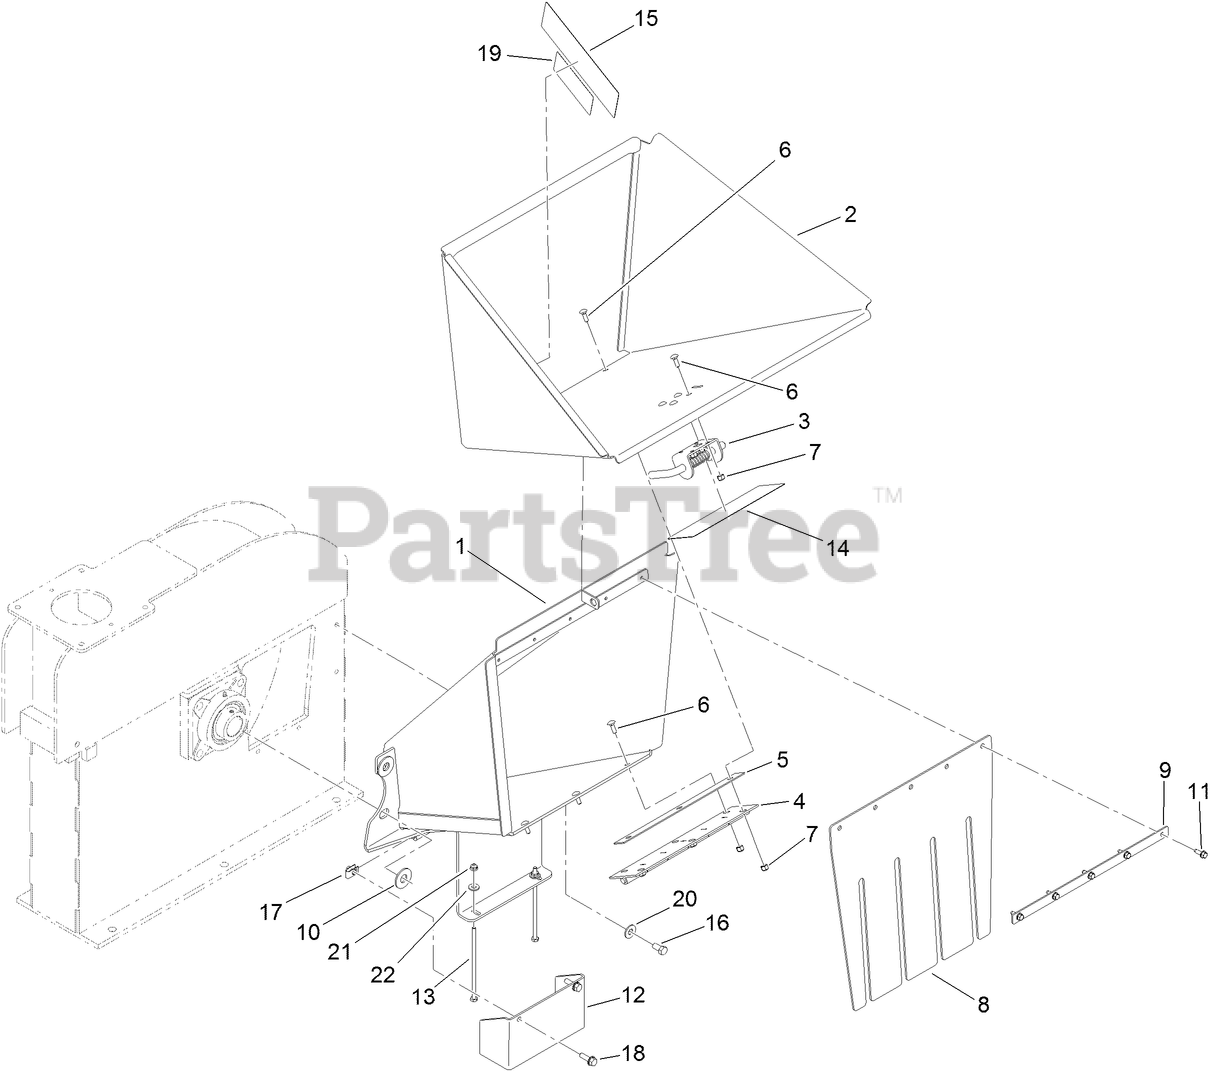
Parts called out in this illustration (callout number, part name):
1	FUNNEL ASM
2	FUNNEL DOOR ASM
3	PIN-LATCHING
4	HINGE-CHUTE
5	PLATE-SHIM, HINGE
6	BOLT-CARR
7	NUT-LOCK, NI
8	FLAP-CHIPPER
9	BAR-FLAP
10	WASHER-FLAT
11	SCREW-HWH, THREAD ROLL
12	BRACKET-COVER, BLADE
13	SCREW-HH
14	DECAL-DANGER
15	DECAL-DANGER
16	SCREW-HH
17	NUT-CLIP, U
18	SCREW-HHF
19	DECAL-LIMIT, LOG
20	WASHER-FLAT
21	NUT-HF
22	WASHER-FLAT
